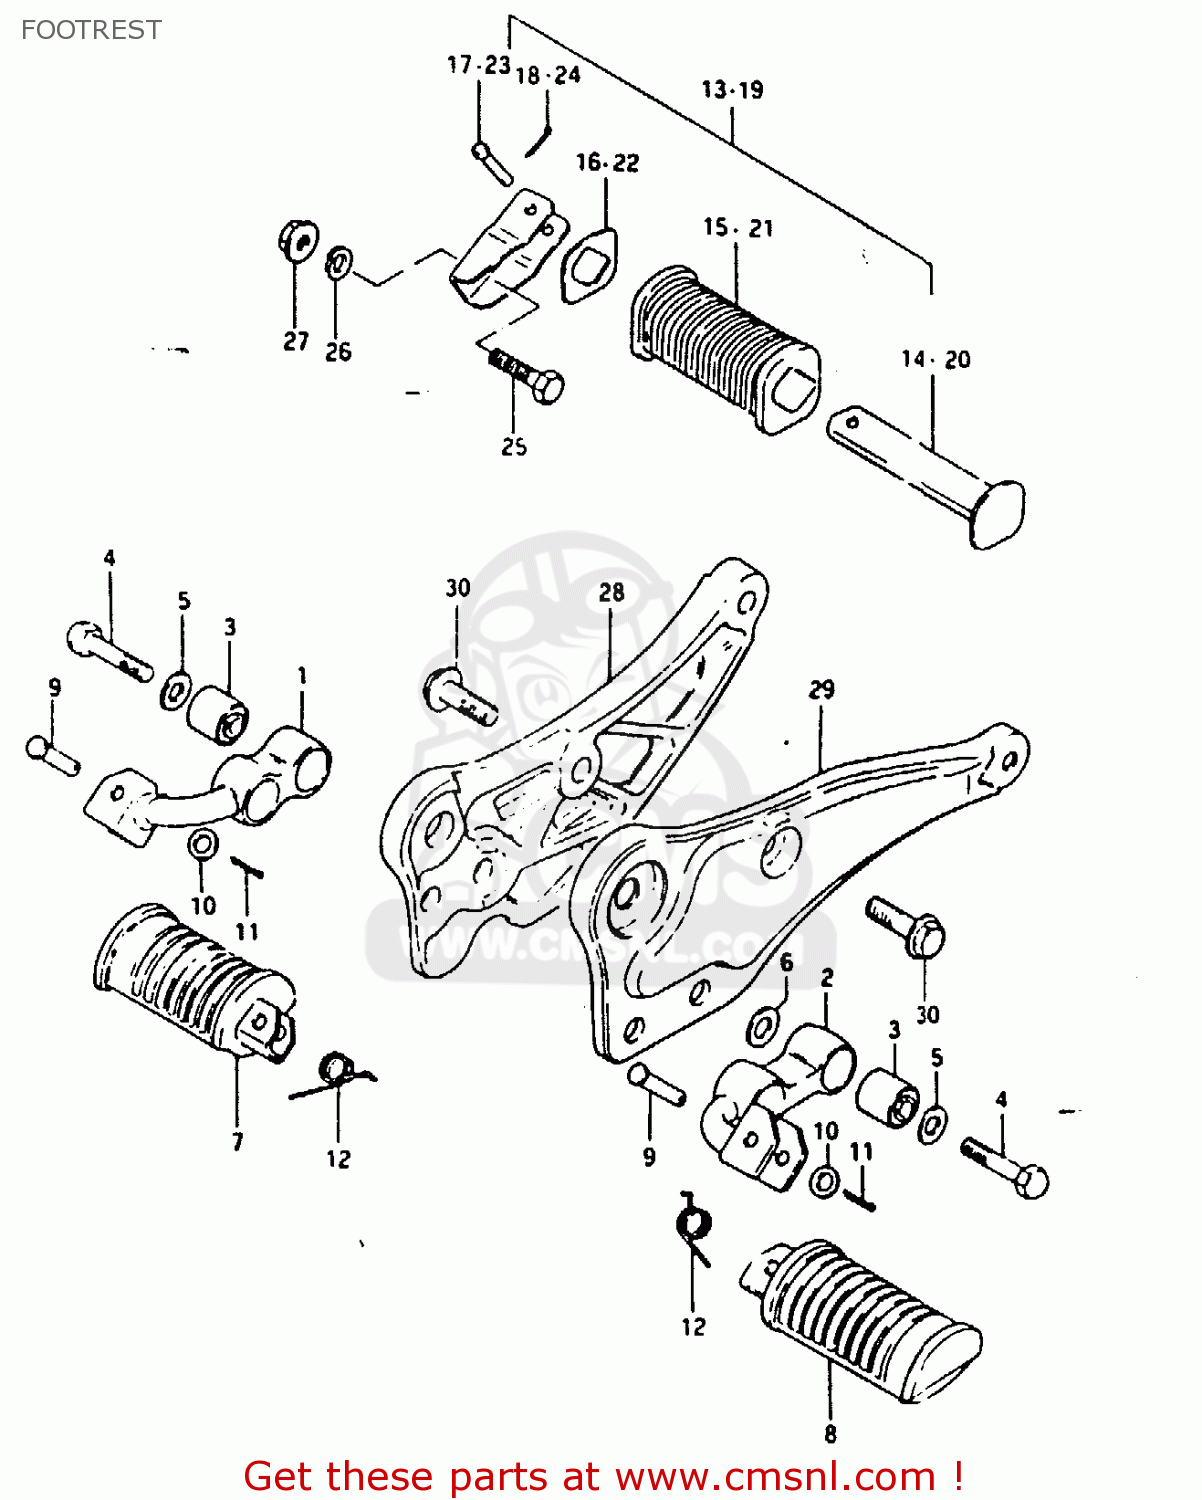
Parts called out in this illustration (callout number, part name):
1	BAR,FRONT FOOTREST
2	BAR,FRONT FOOTREST,LEFT
3	BUSH
4	BOLT(10X50)
5	WASHER
6	WASHER
7	RUBBER,FRONT FOOTREST
8	FOOTREST
9	PIN
10	WASHER
11	PIN
12	SPRING
13	FOOTREST ASSEMBLY,REAR
14	BAR,REAR FOOTREST
15	RUBBER,REAR FOOTREST
16	WASHER,FOOTREST RUBBER
17	PIN
18	PIN
19	FOOTREST ASSEMBLY,REAR,LEFT
20	BAR,REAR FOOTREST,LEFT
21	RUBBER,PILLION FOOTREST
22	WASHER,FOOTREST RUBBER
23	PIN
24	PIN
25	BOLT,M10X1.25X
26	LOCK WASHER
27	NUT
28	BRACKET, MUFFLER RH
29	BRACKET, MUFFLER LH
30	BOLT
